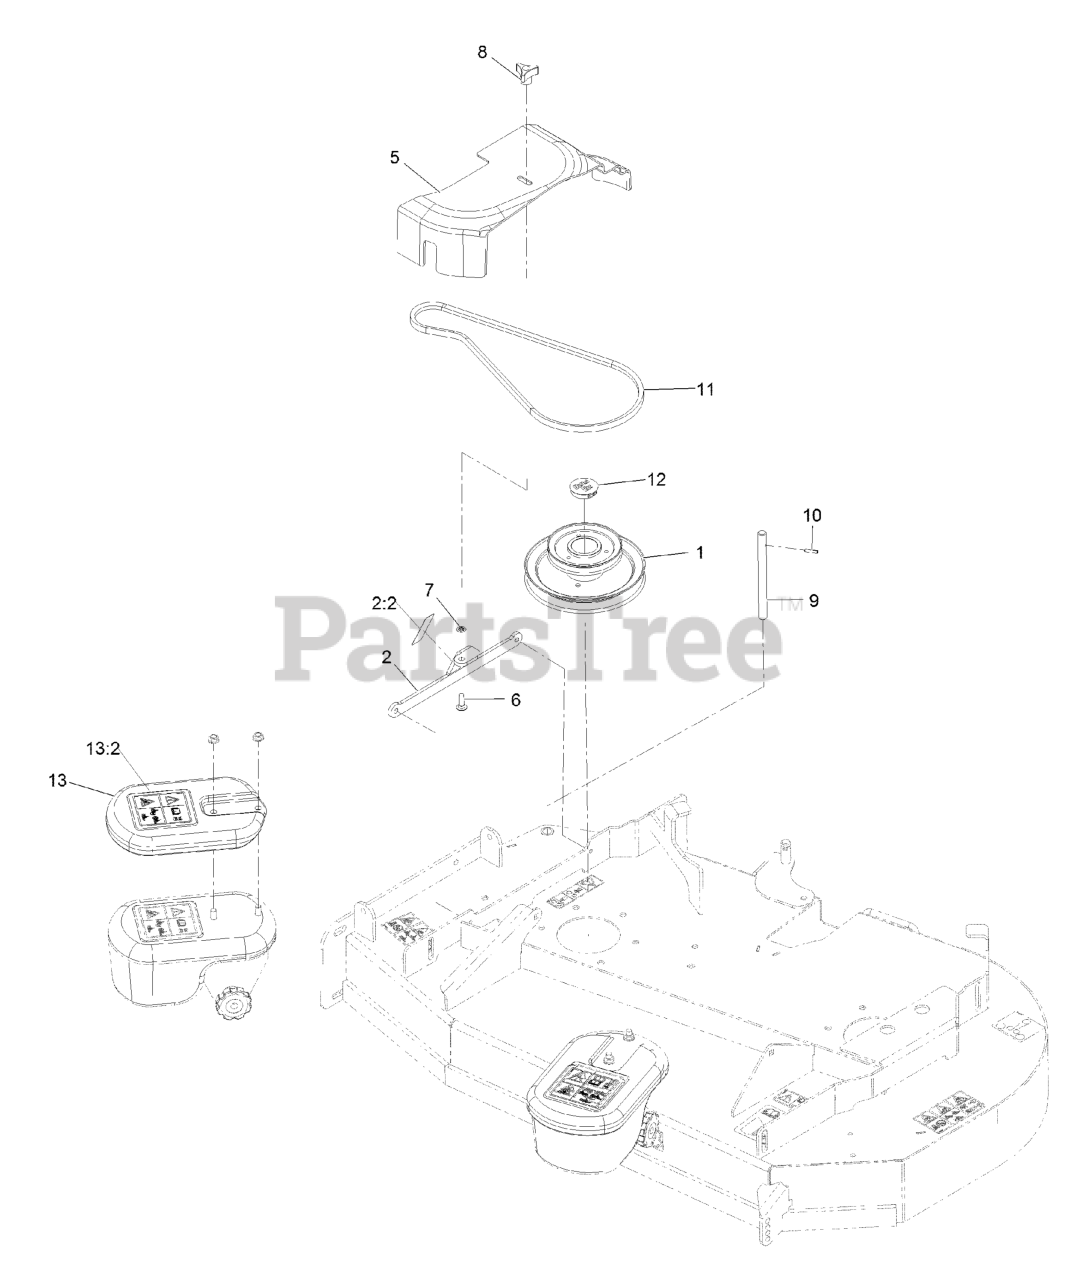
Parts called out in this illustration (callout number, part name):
1	JACKSHAFT- UV DRIVE
2	ASM-CVR BRKT W/DECAL
2:2	DECAL-DANGER
5	COVER-BELT
6	BOLT-CARR
7	RING-RETAINING, BOLT
8	KNOB-3 PRONG
9	SHAFT-CATCHER, GRASS
10	PIN-ROLL
12	PLUG, BLACK NYLON 1.75
13:2	DECAL-WARNING, TRACTION
